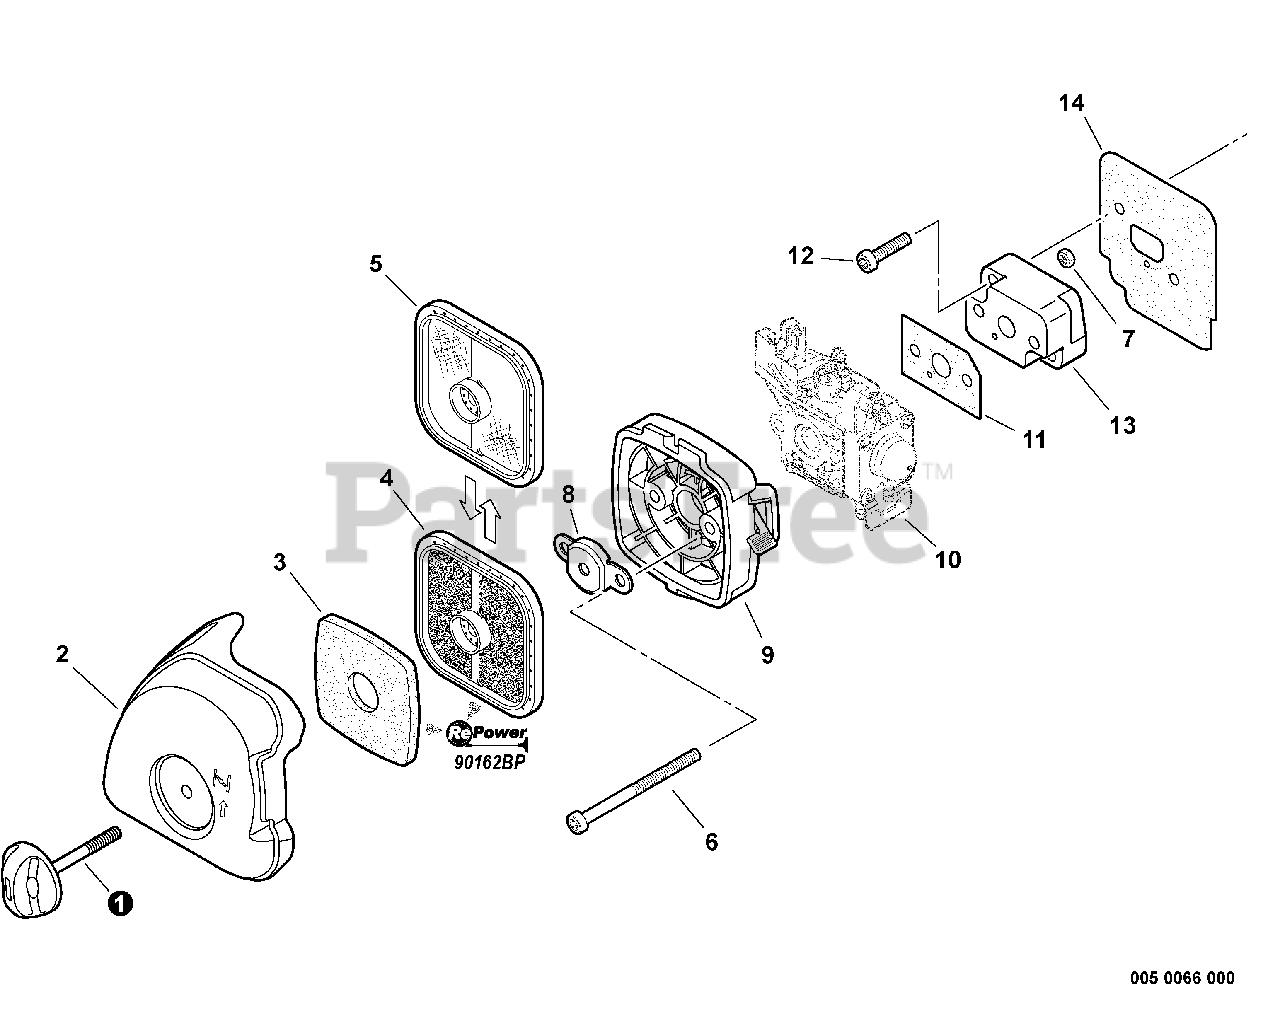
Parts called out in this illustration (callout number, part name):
1	THUMBSCREW
2	COVER, AIR FILTER
3	PRE-FILTER, FOAM
4	FILTER, AIR - DOUBLE LAYER
5	FILTER, AIR - SINGLE LAYER
6	BOLT, TORX 5×65
7	NUT M5
8	PLATE, PREVENT
9	CASE, AIR FILTER
10	CARBURETOR
11	GASKET, INTAKE
12	BOLT, TORX 5×20
13	INSULATOR, INTAKE
14	HEAT SHIELD, INTAKE
15	TUNE-UP KIT - REPOWER
